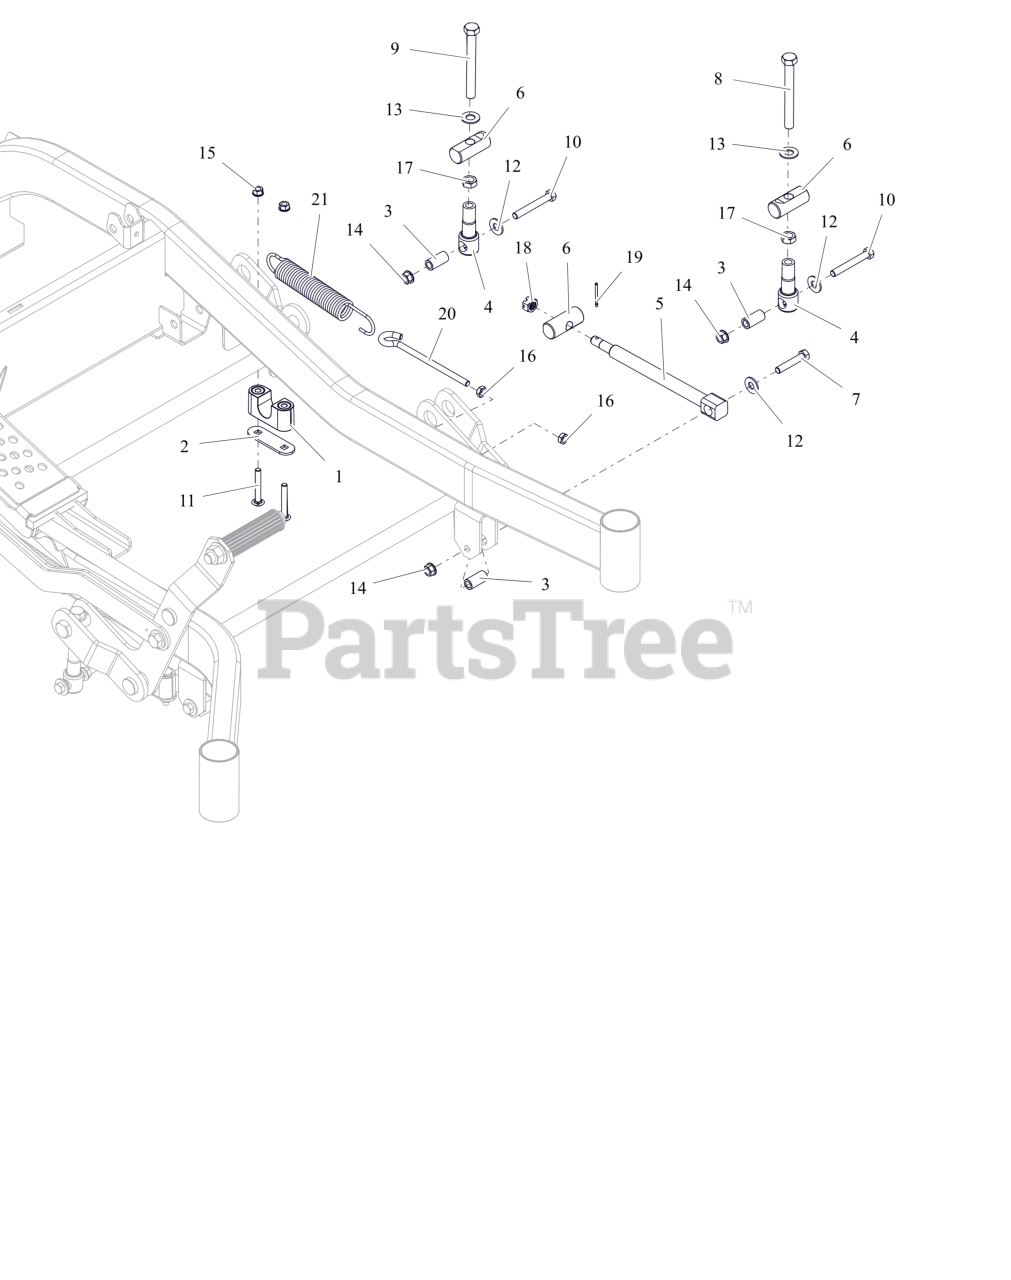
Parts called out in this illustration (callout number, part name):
1	ASM-BUSHING, DECK LIFT
2	PLATE, BEARING SUPPORT
3	SPACER, DECK LEVELING
4	LINK, DECK LIFT FORMED
5	DRAG,LINK-HD
6	PIN, DECK LIFT
7	BLT,HEX .38-16X2.00 G5 ZCC
8	BLT, HEX .50-13X4.50F G8 ZCC
9	BLT, HEX .50-13X4.50F G8 ZCC
10	BLT, HEX .38-16X2.75 G8 ZCC
11	BLT, RHSSN.31-18X2.25 G5 ZCC
12	WSHR,FLT .438X1.00X.083 ZCC
13	WSHR, FLT .557X1.040X.102 ZCC
14	NUT-LK-TOP-FLG .38-16 ZC120
15	NUT,LK-CTR-FLG .31-18 GF ZCC
16	NUT-JAM .375-16 G2 ZCC
17	NUT-JAM .500-13 G2 ZCC
18	NUT-SL .50-13
19	PIN,CTR.12X1.25EXTPRSQCT ZC120
20	BOLT,.38-16 X 5.25-.62 DIA EYE
21	SG-TENS .162X1.25X8.25 WLD 25
